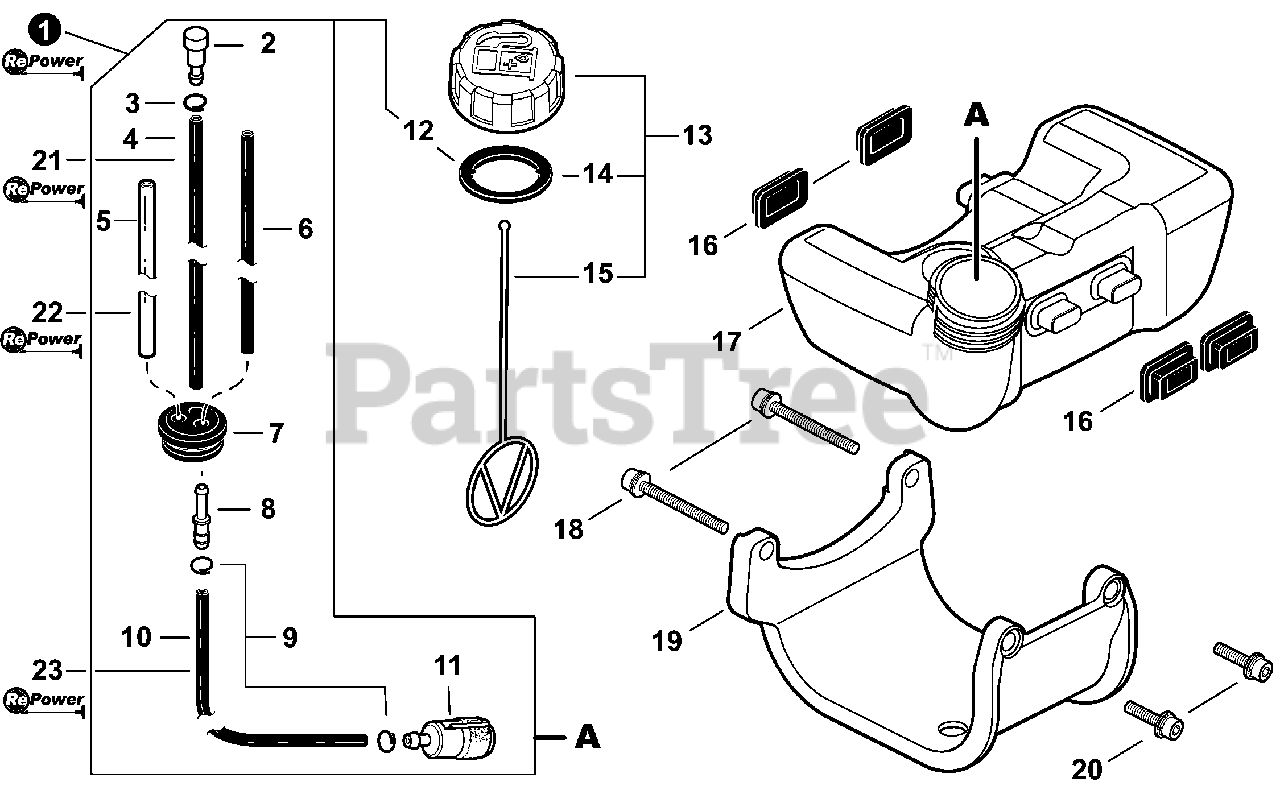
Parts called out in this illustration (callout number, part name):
1	FUEL SYSTEM KIT - REPOWER
2	VENT ASSY
3	CLIP 6.5MM
4	PIPE, FUEL 3×6×105 BLACK
5	PIPE, FUEL 3×6×85 CLEAR
6	PIPE, FUEL 3×5×74 BLACK
7	GROMMET, FUEL
8	CONNECTOR, PIPE 5×3.5
10	PIPE, FUEL 3×5×140 BLACK
11	FILTER, FUEL
12	GASKET, FUEL CAP
13	CAP ASSY, FUEL
14	GASKET, FUEL CAP
15	CONNECTOR, CAP L= 123
16	CUSHION, FUEL TANK
17	TANK, FUEL
18	BOLT 5×40
19	GUARD, FUEL TANK
20	BOLT 5×18
21	PIPE, BULK - 3×6mm BLACK
22	PIPE, BULK - 3×6mm CLEAR
23	PIPE, BULK - 3×5mm BLACK
